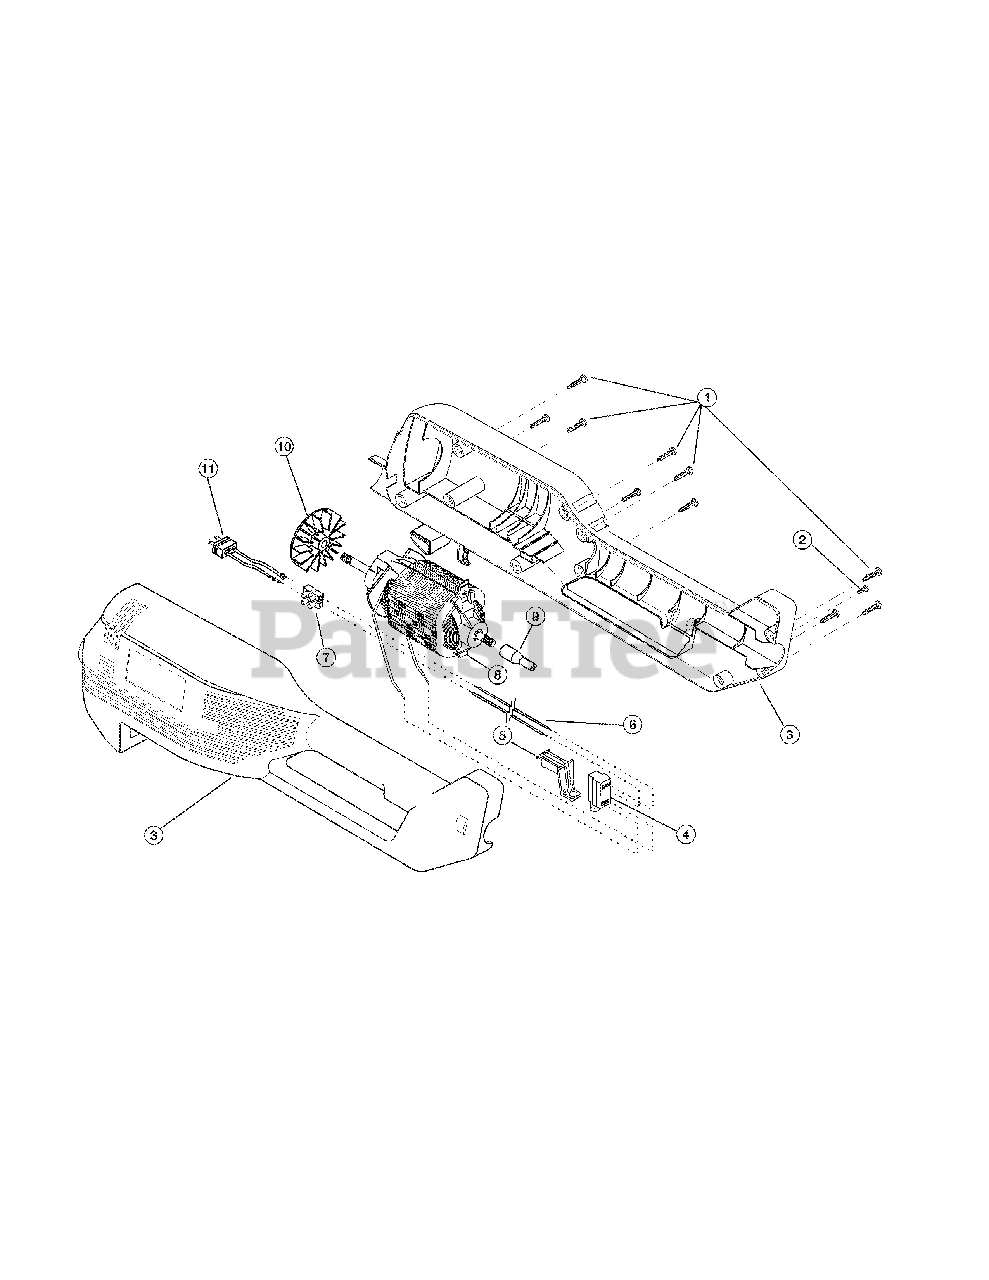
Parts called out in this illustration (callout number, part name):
1	Screw, Housing Set
2	Anti-Rotation Screw
3	Motor Housing Assembly
7	Terminal Block
8	Motor Assembly (includes 9 & 10)
10	Cooling Fan
11	Recessed Plug Assembly
